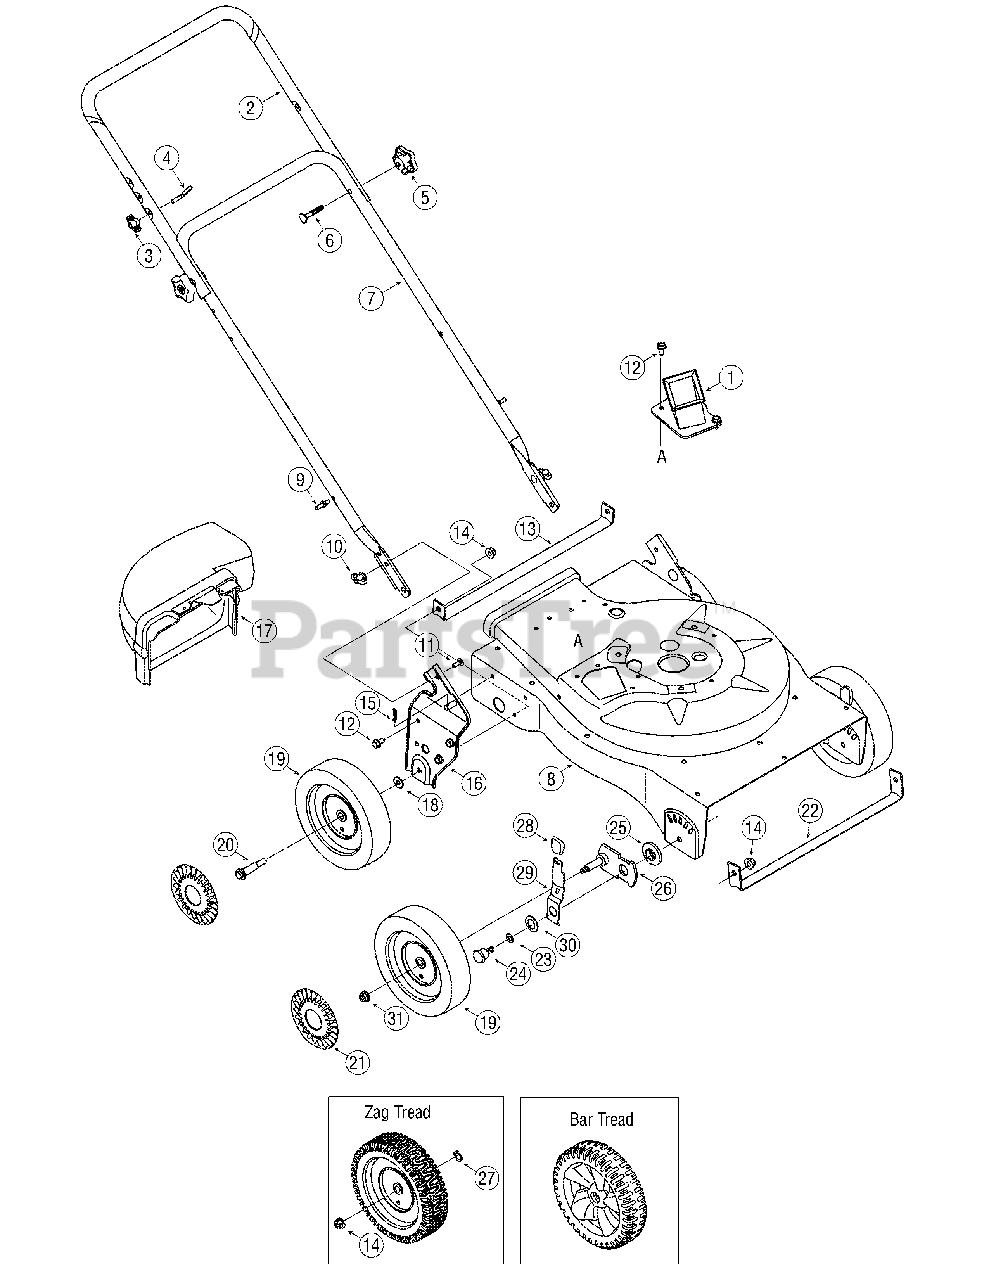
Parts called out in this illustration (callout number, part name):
4	Eye Bolt
5	Star Knob, 5/16-18
6	Carriage Bolt
9	Studs
10	Wing Nut 1/4-20
11	Carriage Screw 1/4-20 x.75
12	Screw, 5/16-12 x.750
14	Flange Lock Nut, 3/8-16
15	Cotter Pin
17	Blower Chute Assembly
18	Bell Washer.401 ID x.870 OD
19	Wheel, 8 x 1.8, Bar
19	Wheel, 8 x 2.125, Zag
20	Shoulder Screw 3/8-16
21	Hub Cap
23	Thrust Washer.375 ID x.70 OD
24	Shoulder Screw, .750 ID x .500
25	Height Adjustment Bearing
26	Pivot Arm Assembly
27	Wave Washer, .531 ID x .781 OD
28	Height Adjustment Knob
29	Spring Lever
30	Bell Washer.760 ID x.25OD
31	Flange Lock Nut, 3/8-16
